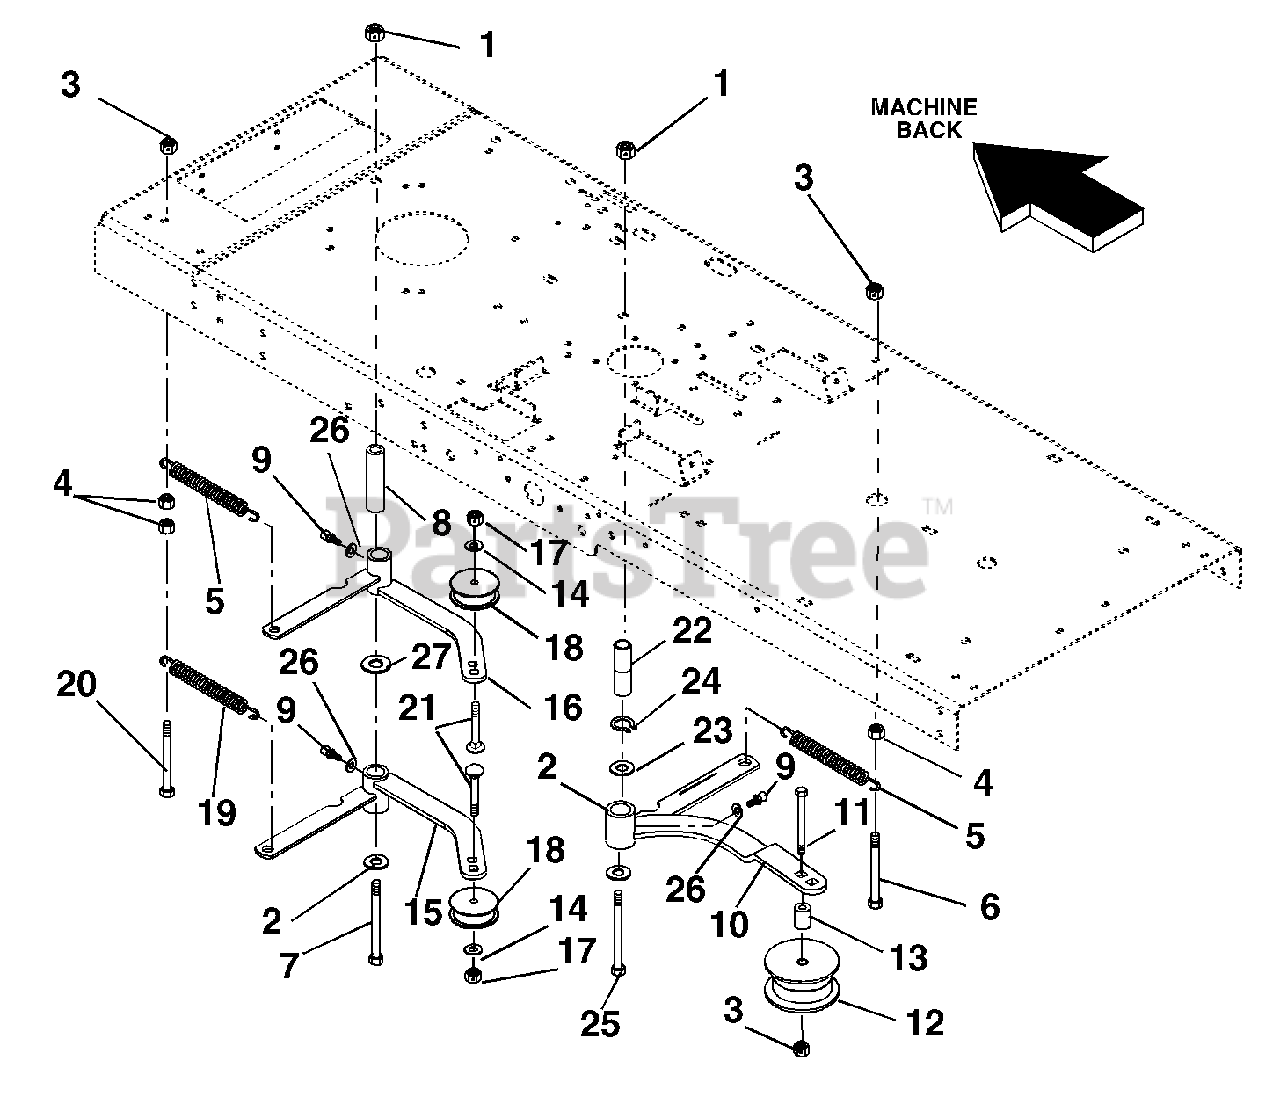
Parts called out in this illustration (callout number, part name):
1	@NUT-LK-TOP-FLG .50-13 YWZC
2	@WSHR-FL-STL.563X1.38X.109YWZC
3	@NUT-LK-TOP-FLG .38-16 YWZC
4	@NUT-HEX .38-16 YWZC
5	SPRING, EXT
6	@BLT-HEX .38-16X4.00 GR5 YWZC
7	@BLT-HEX .50-13X5.50 GR5YWZC
8	SPACER, IDLER
9	FTG-LUBE .25-28X.256 YWZC
10	WELDMENT, IDLER ARM
11	@BLT-HEX .38-16X4.50 GR5 YWZC
11	@BLT-HEX .38-16X2.50 GR5 YWZC
12	IDLER 4.0" DIA
13	SPACER, IDLER - 48"
14	@WSHR-FL-STL.406X.812X.065 YWZ
15	IDLER ARM WLDM'T TRANSAXLE
16	WLDM'T JACKSHAFT IDLER ARM
17	@NUT-LK-CTR-JAM .375-16 YWZC
18	PULLEY, IDLER 4.00
19	SPRING, EXTENSION
20	@BLT-HEX .38-16X4.50 GR5 YWZC
21	@BLT-RDHDSQNK .38-16X1.50 G5YZ
22	SPACER, IDLER
23	WSHR-FL-STL .880X1.250X.062YWZ
24	RG-RTNG-EXT .875X.042
25	@BLT-HEX .50-13X4.50 GR5 YWZC
26	@WSHR-FL-STL.250X.56X.049 YWZC
27	WASHER, .937 X 2.25 YWZC
